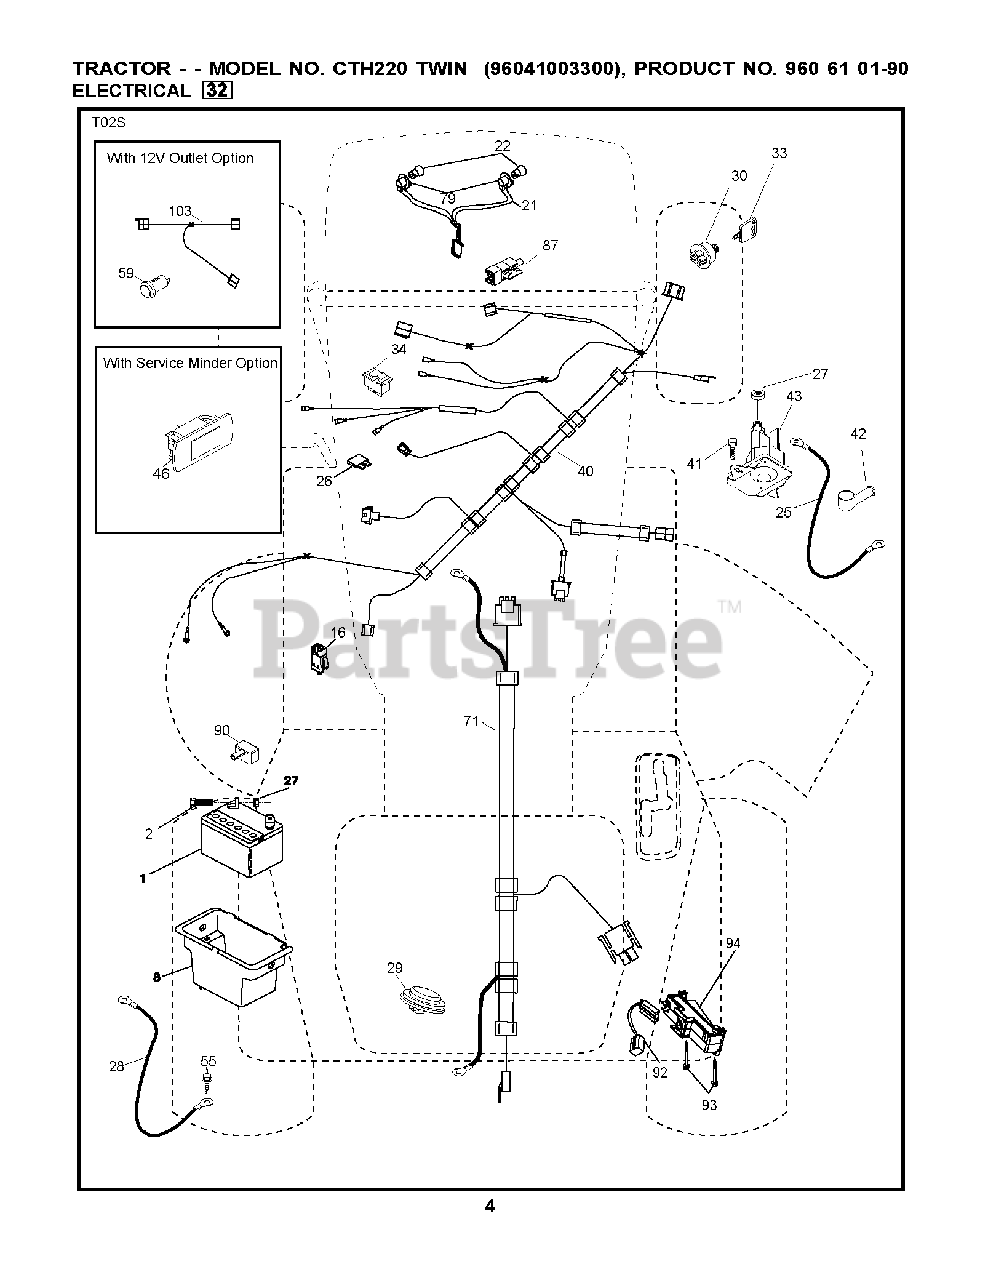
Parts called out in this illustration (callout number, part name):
1	BATTERY 12V .35 AMP
7	BULB HOLDER ASM.
8	BOX.BATTERY.MNT.REAR.L
16	SWITCH INTERLOOK PUSH-IN
21	HARNESS ASSY LIGHT
22	LIGHTBULB
25	CABLE.STARTER.6GA.RED.
26	FUSE 20AMP
27	NUT
28	CABLE.BLACK.18"REAR.BA
29	SWITCH.SEAT.DELTA.OPC.
30	SWITCH.IGN.DELTA.W.LGH.ROS
33	KEY MLD GEN DELTA
34	SWITCH LT
40	HARNESS.IGN.CHASS.TEX.REAR.BAT
41	SCREW
42	TERMINAL COVER
43	SOLENOID.W/BRASS.PLUNG
55	SCREW 5/16"
71	HARNESS IGN. DASH
87	SWITCH.INTRLCK.CLUTCH.
90	COVER, TERMINAL BATTERY
92	HARNESS.PIGTAIL.CONSLE
93	SCREW.PLASTITE
94	MODULE.REVERSE.ROS
